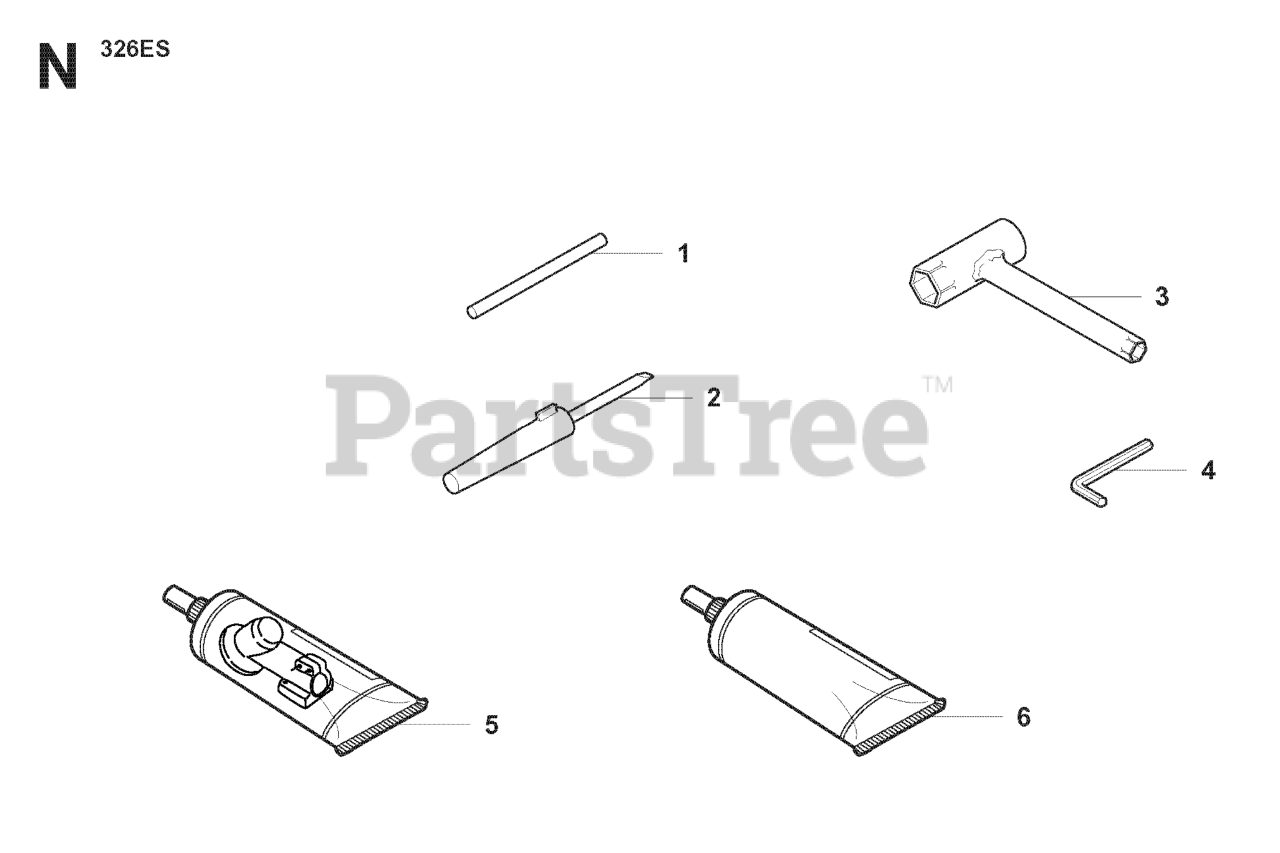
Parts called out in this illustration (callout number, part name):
1	LOCKING PIN
2	SCREWDRIVER
3	COMBI WRENCH
4	L-KEY WRENCH
5	BEVEL GEAR GREASE
6	DRIVE SHAFT GREASE (200 G)
